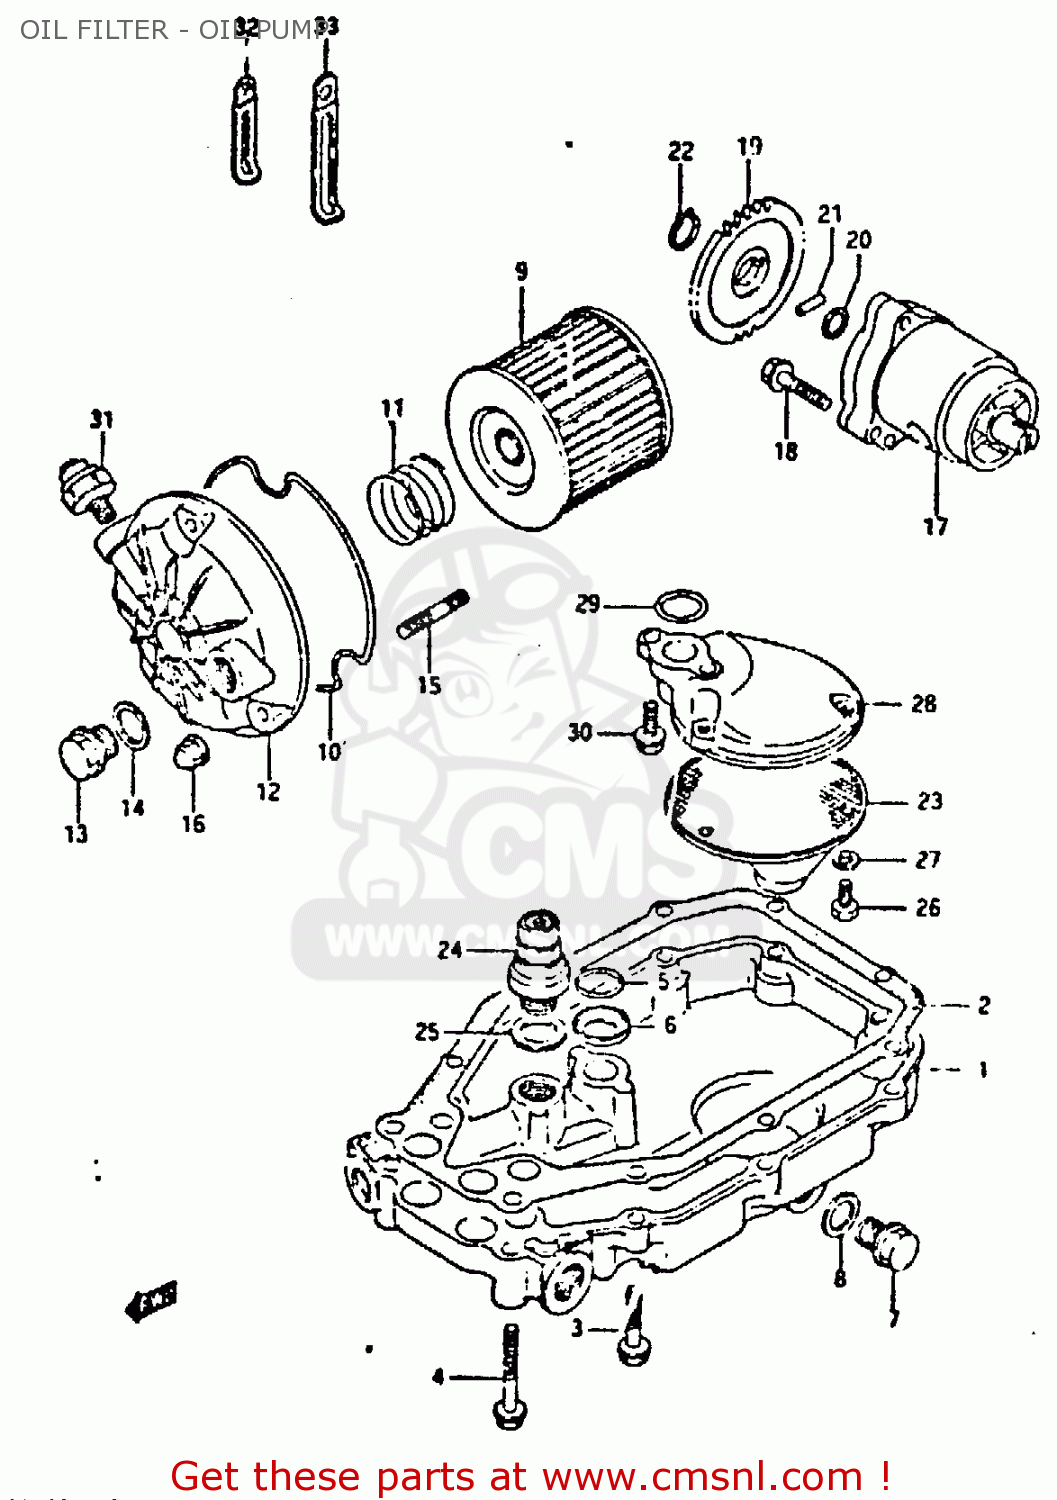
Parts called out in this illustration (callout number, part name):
1	PAN,OIL
2	PAKKING.OLIEPAN
3	BOLT
4	BOLT
5	O RING(D:3.2,ID:15.8)
6	GASKET,OIL OUTLET (NAS)
7	PLUG
8	GASKET, STOPPER HOUSING
9	FILTER ASSY,ENGINE OIL
10	O RING,OIL FILTER CHAMBER CAP
11	SPRING
12	CAP.OIL FILTER
13	PLUG(14X12)
14	GASKET(14X19.2X2) (NAS)
15	STUD BOLT L:20
16	NUT
17	PUMP ASSY,ENGINE OIL
18	BOLT
19	GEAR,OIL PUMP DRIVEN
20	SHIM
21	PIN(5X18)
22	CIRCLIP
24	VALVE ASSEMBLY,OIL RELIEF
25	GASKET(16X22X2) (NAS)
26	BOLT
27	WASHER,LOCK
28	PROTECTOR,OIL STRAINER
29	O RING(D:3.2,ID:15.8)
30	BOLT,REAR
32	CLAMP
33	CLAMP
